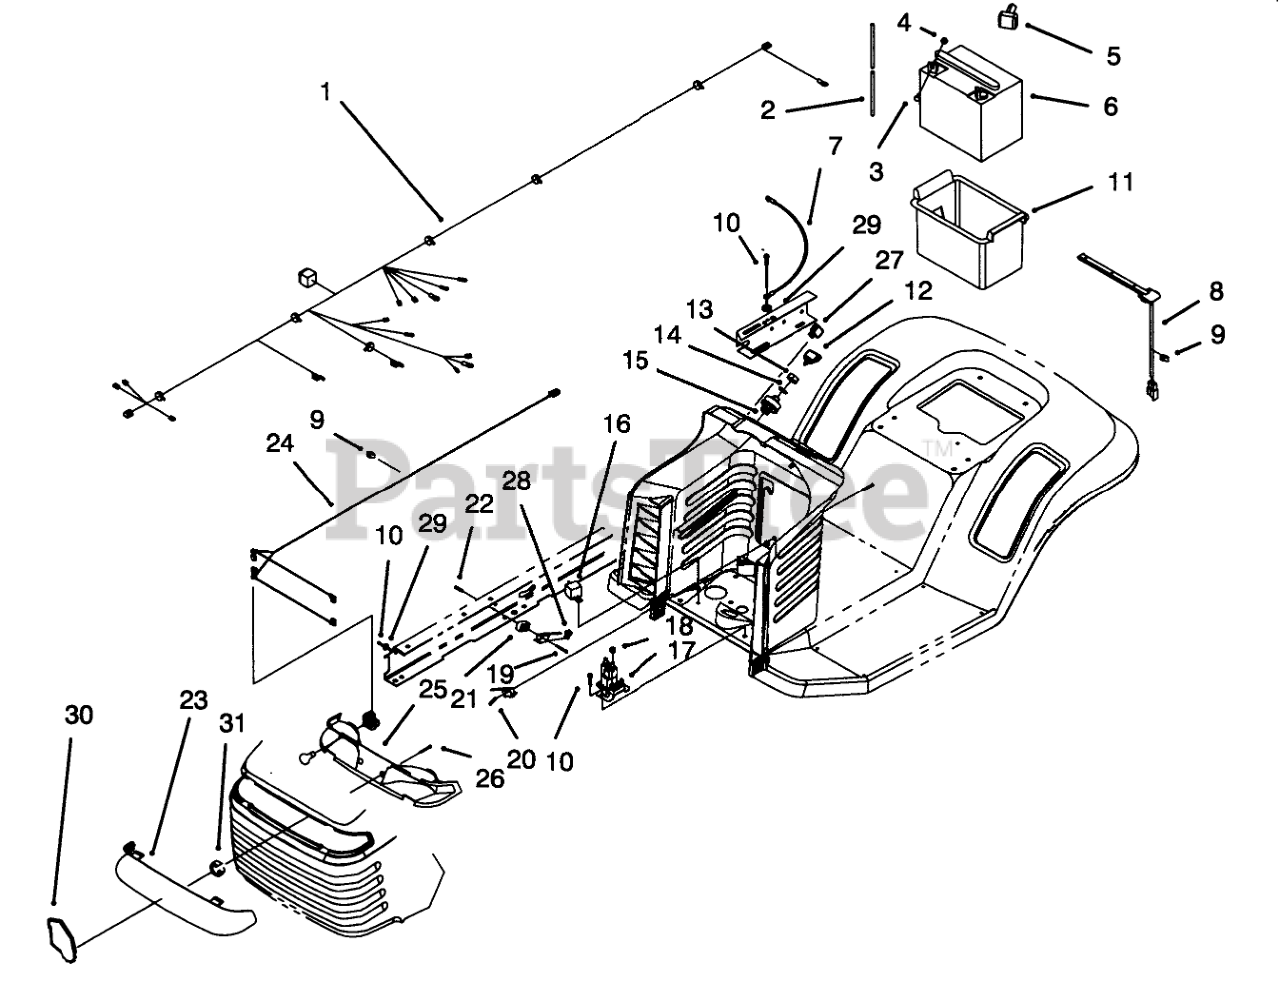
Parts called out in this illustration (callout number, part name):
1	Harness-Wire
2	TUBE-BATT DRAIN/80-2600
3	SCREW-HH
4	NUT-WING
5	BOOT-TERMINAL
6	Battery
7	WIRE ASM
8	SWITCH-SEAT
9	CLIP-RETAINER, WIRE
10	SCREW-HWH
11	BOX-BATTERY
12	KEY-IGNITION
13	NUT-HH
14	WASHER-TOOTH, INTERNAL
15	Key Switch ASM
16	RELAY
17	SOLENOID
18	NUT-KEPS
19	Screw
20	SWITCH-MICRO
21	SPACER
22	NUT-SPEED
23	LENS-HEADLIGHT
24	HARNESS-WIRE, LIGHTS
25	HEADLIGHT REFLECTOR ASM
27	SWITCH-ROCKER
28	Seal-Plunger
29	WASHER-LOCK/EXT
30	EMBLEM-GRILLE WHEELHORSE
